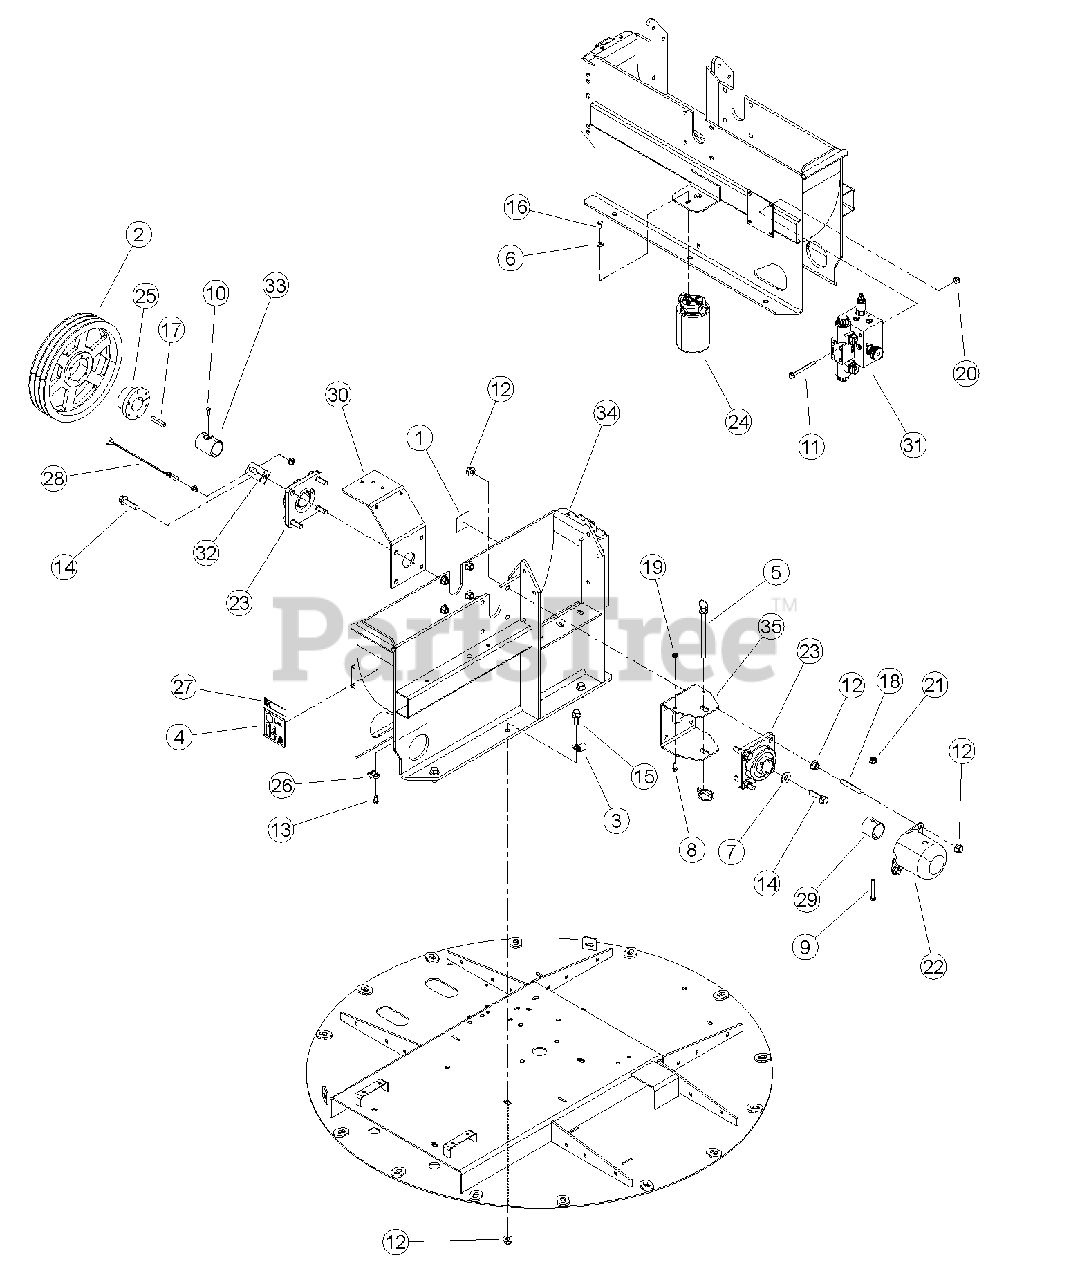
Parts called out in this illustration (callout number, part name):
1	DECAL, SHIELD DANGER ISO
2	SHEAVE, 3BQ12.4, SK
3	CLAMP, 9/16 COATED
4	DECAL, 114 DB (CE COMPLIANT ONLY)
5	PIN, HITCH 1/2 X 6-1/2 W/ LYNCH
6	WASHER, 1/4" FLAT ZP
7	WASHER, 1/2" FLAT ZP
8	BOLT, 1/4-20 X3 /4 HWH GR5 CZP
9	BOLT, 3/8 X 2-1/2 GR5 HHCS ZP
10	SCREW, 5/16-18 X 5/8 SQ HD SET
11	BOLT, 5/16 X 3-1/2 SERRATED FLANGE NC
12	NUT, 1/2-13 NYLOCK FLANGE
13	SCREW, 11/32 X 7/8 HWH AB THREAD ZP
14	BOLT, 1/2-13 X 2 HWH GR5 CZP
15	BOLT, 1/2 -13 X 1-1/4 FLANGE NC
16	BOLT, 1/4 X 5/8" HHCS GR5 ZP
17	KEY, 3/8" SQ X 2" LG PLAIN
18	STUD, 1/2"-13 X 3" LG B7 ZP
19	NUT, 1/4-20 NYLOCK-FLANGE
20	NUT, 5/16-18 NYLOCK-FLANGE
21	NUT, 3/8-16 NYLOCK FLANGE
22	CAP, LARGE SHAFT
23	BEARING, 1-3/4 4 BOLT FLANGE
24	ASSEMBLY, HYDRAULIC FILTER
25	BUSHING, SK 1-3/4"
26	CLAMP, CABLE MOUNT
27	DECAL, CH8720IH INFORMATION (CE COMPLIANT ONLY)
28	SENSOR, M12 PNP PROXIMITY (REPLACEMENT PART)
29	COLLAR, CHIPPER LOCK
30	WELDMENT, REAR GUARD SUPPORT
31	ASSEMBLY, HYDRAULIC FEED FLOW VALVE W/ PS
32	BRACKET, PROXIMITY SENSOR
33	WELDMENT, SPACER 2.0 X 2.30
34	WELDMENT, CHIPPER BOTTOM
35	BRACKET, ROTOR LOCK
